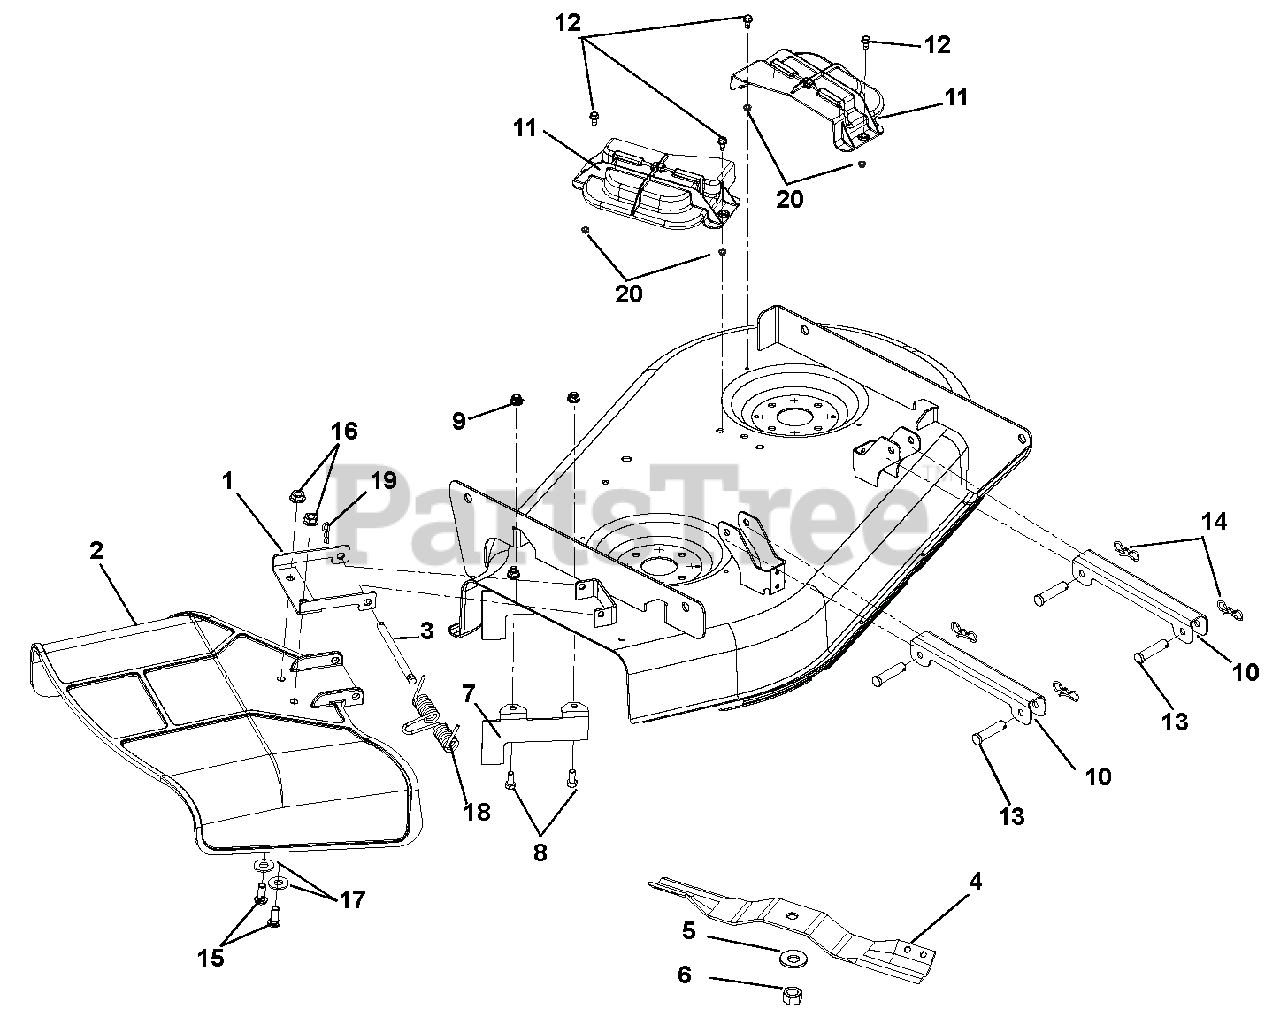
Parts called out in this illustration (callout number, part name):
1	CHUTE REINFORCEMENT
2	CHUTE, SIDE DISCHARGE
3	PIN, 5/16 X 3.88"
4	BLADE-17.34 OS MULCH
5	WSHR-BLVL .669X1.535X.138
6	NUT-HEX .62-18 YWZC
7	BRKT-BAFFLE, DISCHARGE 34"
8	@BLT-HEX .31-18X.75 GR5 YWZC
9	@NUT-LK-NYL-FLG .31-18 YWZC
10	BRKT-STABILIZER LINK
11	COVER-BELT, MOLDED
12	SCR-TAP .25-20X.50 HWH TR YWZ
13	PIN-CLEV .375 X 2.00 YWZC
14	PIN, BOW TIE LOCKING
15	SCR-SKH .31-18X.75 BTNHD YWZC
16	@NUT-LK-TOP-FLG .31-18 YWZC
17	@WSHR-FL-STL.38X.875X.083 YWZC
18	SPRING, TORSION
19	PIN-HAIR INT .08X.18X1.18 YWZC
20	NUT-PUSH .25X.50 O.D.
